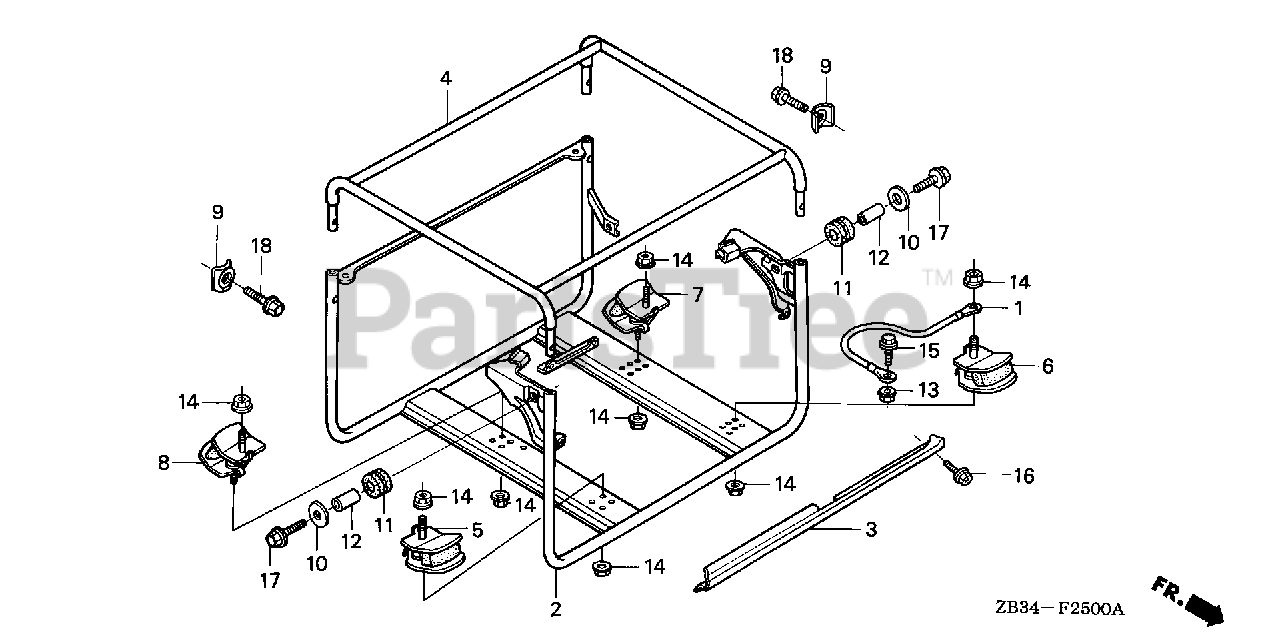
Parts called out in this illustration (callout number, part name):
1	CABLE, GROUND
2	FRAME (LOWER) *NH105* (MAT BLACK)
3	CHANNEL, FR. *NH105* (MAT BLACK)
4	FRAME (UPPER)
5	RUBBER, RR. (LOWER)
6	RUBBER, FR. (LOWER)
7	RUBBER, FR. (LOWER)
8	RUBBER, RR. (LOWER)
9	WASHER, FRAME JOINT
10	WASHER, FLAT (20MM)
11	RUBBER, CONTROL BOX
12	COLLAR, CONTROL BOX
13	NUT, FLANGE (6MM)
14	NUT, FLANGE (8MM)
15	BOLT, FLANGE (6X10)
16	BOLT, FLANGE (6X12)
17	BOLT, FLANGE (6X20)
17	BOLT, ADJUSTING (6X20)
18	BOLT, FLANGE (8X14)
